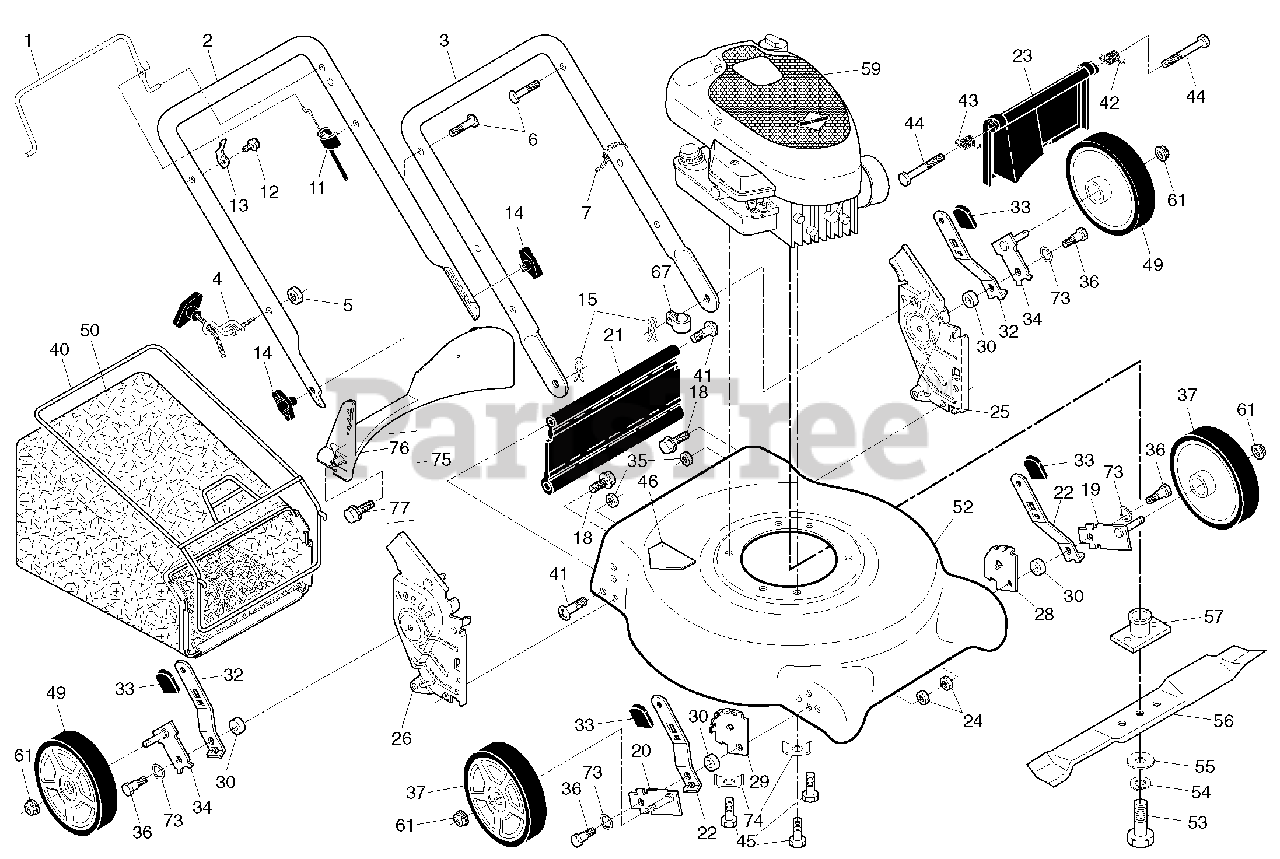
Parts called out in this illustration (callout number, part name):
1	Control Bar
2	Upper Handle
3	Lower Handle
4	Rope Guide
6	Handle Bolt
7	Wire Tie
11	Cable, Engine Zone Control
12	Hex Washer Head Screw
13	Up-Stop Bracket
14	Knob, Handle
15	Hairpin Cotter
18	Screw
19	Axle Arm Assembly, Front, LH
20	Axle Arm Assembly, Front, RH
21	Kit, Rear Skirt
22	Selector Spring, Front
23	Rear Door Assembly
24	Nut, Hex 5/16-18
25	Handle Bracket Assembly, LH
26	Handle Bracket Assembly, RH
28	Wheel Adjusting Bracket, Front, LH
29	Wheel Adjusting Bracket, Front, RH
30	Spacer
32	Selector Spring, Rear
33	Selector Knob
34	Axle Arm Assembly, Rear, LH
35	Locknut, Hex 5/16-18
36	Shoulder Bolt 5/16-18
37	Wheel & Tire Assembly, Front 7 x 1-3/4
40	Frame, Grassbag
41	Hinge Screw
42	Spring, Rear Door, LH
43	Spring, Rear Door, RH
44	Bolt, Rear Door
45	Hex Head Thread Rolling Screw 3/8-16 x 1
46	Danger Decal
49	Wheel & Tire Assembly, Rear 8 x 1-3/4
52	Kit, Mower Housing
53	Hex Head Screw 3/8-24 x 1-3/8 Grade 8
54	Helical Lockwasher
55	Hardened Washer
56	21" Blade
57	Blade Adapter
61	Flanged Locknut, Hex
67	Clip, Cable
73	Washer, Curved, Cylindrical
74	Washer, Special, Engine
75	Kit, Rear Baffle
76	Baffle, Rear
77	Screw, Rear Baffle
